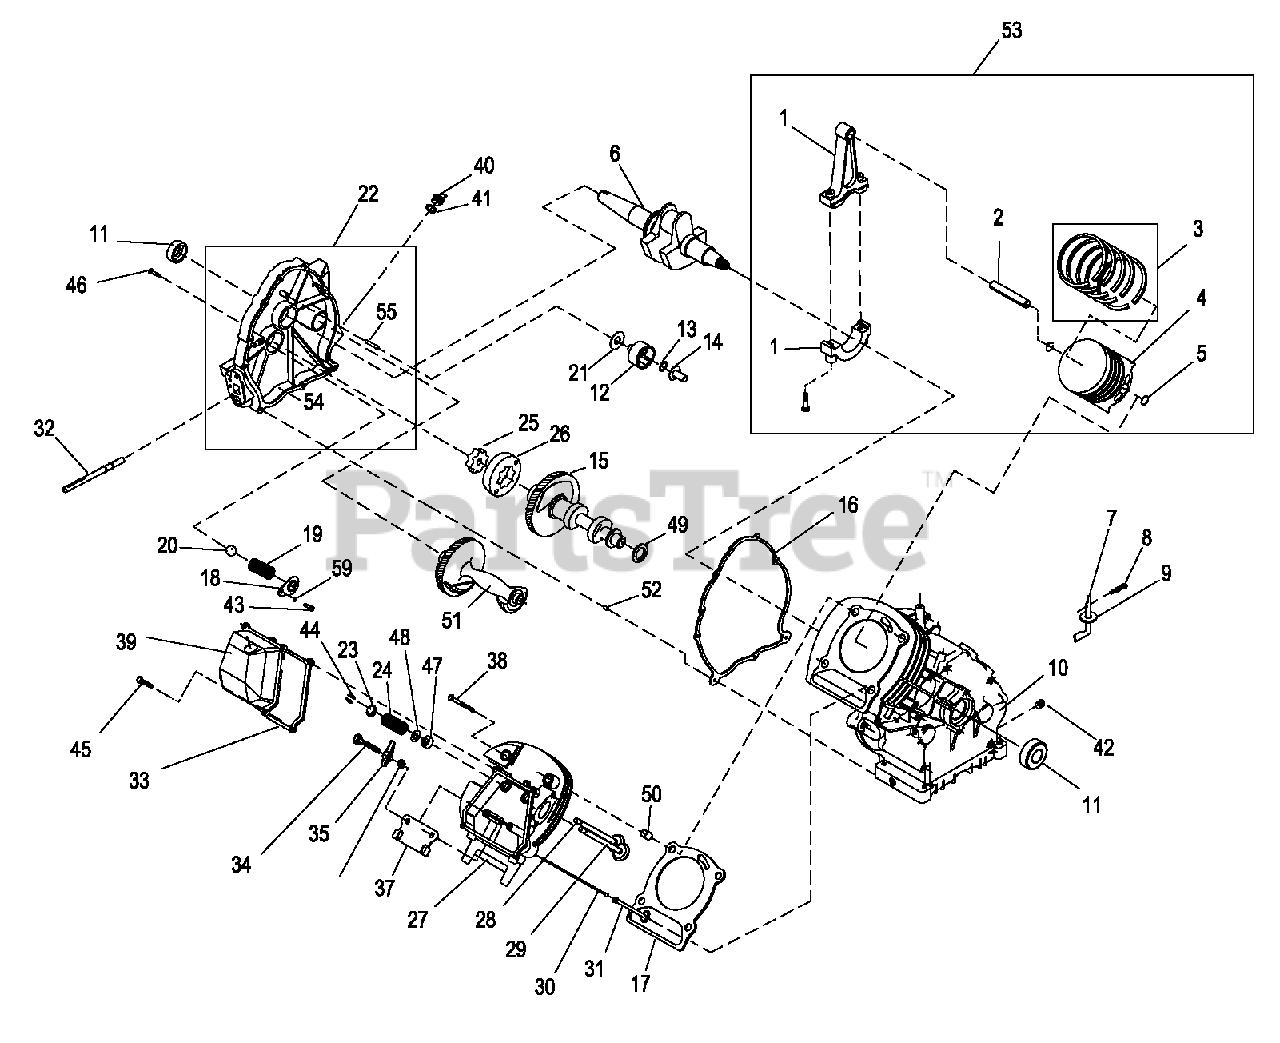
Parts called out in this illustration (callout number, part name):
1	ASSEMBLY, CONNECTING ROD
2	PIN, PISTON D20
3	RING SET, PISTON DIA90
4	PISTON, FLAT TOP DIA90 COATED
5	RETAINER, PISTON PIN 20
6	CRANKSHAFT SAE PTO TAPER LF
7	ARM, GOVERNOR RC45
8	PIN, "R" GOVERNOR ARM
9	WASHER, GOVERNOR ARM THRUST
10	CRANKCASE, SUBASSEMBLY WITH PLUGS GH410
11	SEAL, 35 I.D. CRANKSHAFT
12	ASSEMBLY, GOVERNOR GEAR
13	C-RING, GOVERNOR GEAR RETAINER
14	SPOOL, GOVERNOR- MACHINE
15	ASSEMBLY, CAMSHAFT & GEAR
16	GASKET , CRANKCASE
17	GASKET, HEAD 410
18	COVER, OIL PRESSURE RELIEF
19	SPRING, OIL RELIEF 360
20	BALL, DIA 11/32 PRESSURE RELIEF
21	WASHER, THRUST GOVERNOR GEAR
22	ASSEMBLY, COVER
23	RETAINER, VALVE SPRING
24	VALVE SPRING LF
25	GEROTOR, INNER 12 THK
26	GEROTOR, OUTER 12 THK
27	ASSEMBLY,CYLINDER HEAD SEATS & GUIDES
28	VALVE, EXHAUST
29	VALVE, INTAKE
30	PUSH ROD 174.9
31	TAPPET
32	ASSEMBLY, SCREEN OIL PICK-UP
33	GASKET, ROCKER COVER 410
34	STUD, D20 PIVOT BALL
35	ROCKER ARM
36	NUT, JAM M8 (ROCKER ARM)
37	PLATE, PUSH ROD GUIDE
38	SCREW, HHFL M10-1.5 X 105
39	ASSEMBLY, ROCKER COVER OHVI
40	PLUG, OIL FILL PLASTIC
41	O-RING 11/16 – 7/8
42	PLUG, STANDARD PIPE 3/8 STEEL SQUARE HEAD
43	SCREW HHC M5-0.8 X 10 C8.8
44	KEEPER, VALVE SPRING
45	SCREW & LOCKWASHER M6-1 X 12
46	SCREW, HHFC M8-1.25 X 42
47	SEAL, VALVE STEM D7
48	WASHER, VALVE SPRING
49	WASHER, LARGE WAVE
50	SLEEVE, DOWEL PIN 14 DIA.
51	BALANCER
52	SLEEVE, DOWEL PIN 12 DIA.
53	ASSEMBLY, PISTON PIN & CONNECTING ROD
54	GEARCOVER, MACHINED
55	SHAFT, GOVERNOR
56	PLUG, 6.5 DIA.
57	PLUG, 8.4 DIA.
58	SHAFT, BEARING TUBE
59	WASHER, LOCK M5
